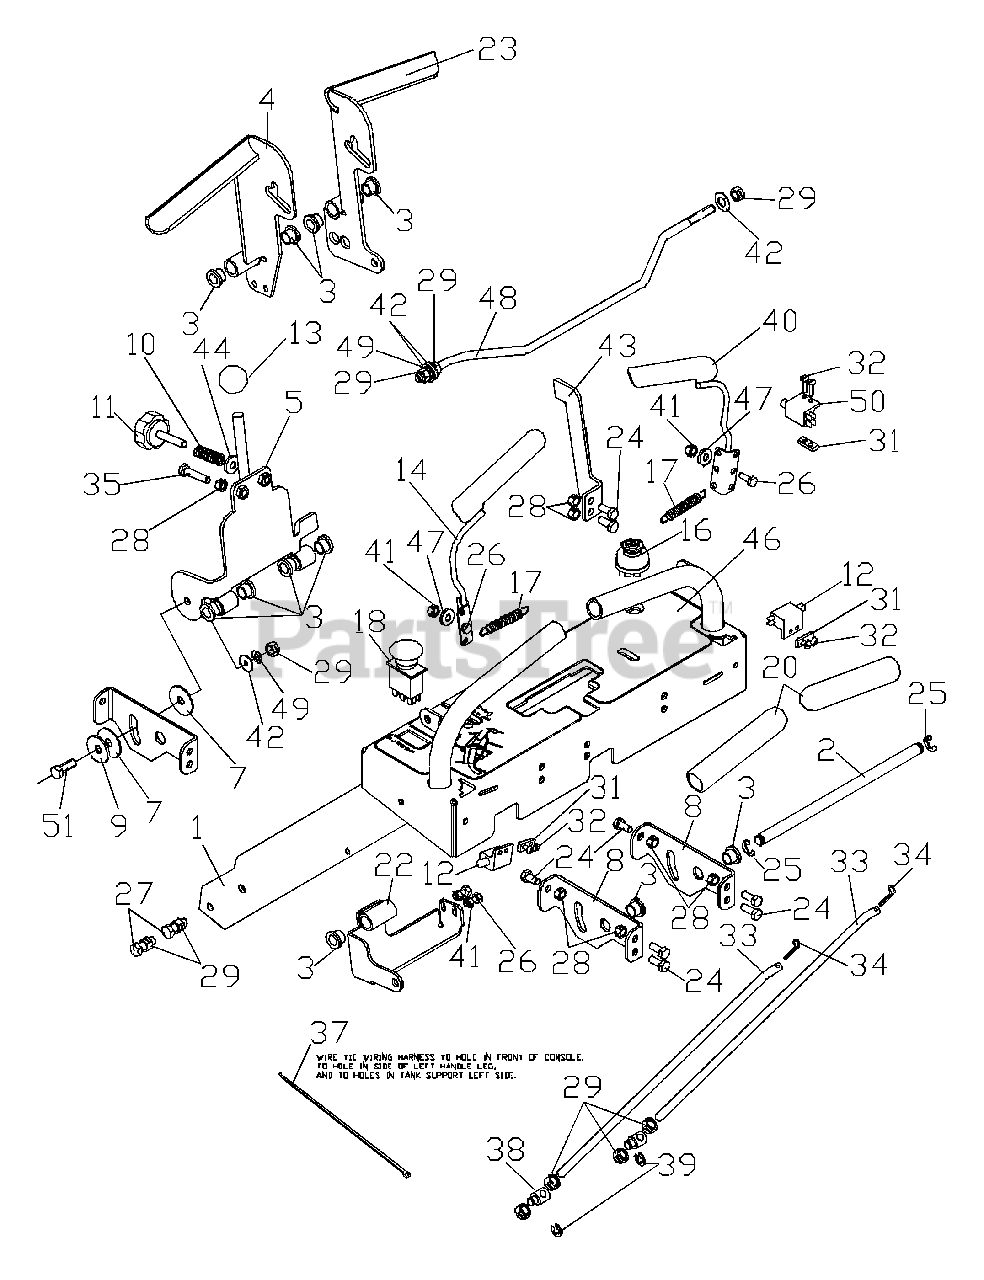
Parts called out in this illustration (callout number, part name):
3	FLANGE BUSHING
4	PADDLE LH.
5	NEUTRAL BAR
7	FRICTION WASHER
8	CROSSBRACE
9	WASHER 1/2 FLAT
12	SWITCH N.C.
14	OP LEVER LH.
16	IGNITION SWITCH
18	CLUTCH SWITCH
22	TAB WLDMT. LH.
23	PADDLE RH.
24	HCS 5/16 X .750
25	E-RING 1/2
26	HCS 1/4 X .625
27	HCS 3/8 X 1.000
28	NUT 5/16 CTR. LOCK
29	NUT 3/8 CTR. LOCK
31	TAPPED PLATE
32	SCREW #10-24
34	COTTER PIN
35	HCS 5/16 X 1.250
40	OP LEVER RH.
41	NUT 1/4 CTR. LOCK
42	WASHER 3/8 FLAT
43	STOP PLATE
44	WASHER 5/16 FLAT
46	CONSOLE DECAL
47	WASHER 1/4 FLAT
48	NEUTRAL BAIL
49	WASHER 3/8 LOCK
50	SAFETY SWITCH
51	HCS 3/8 X 1.250
